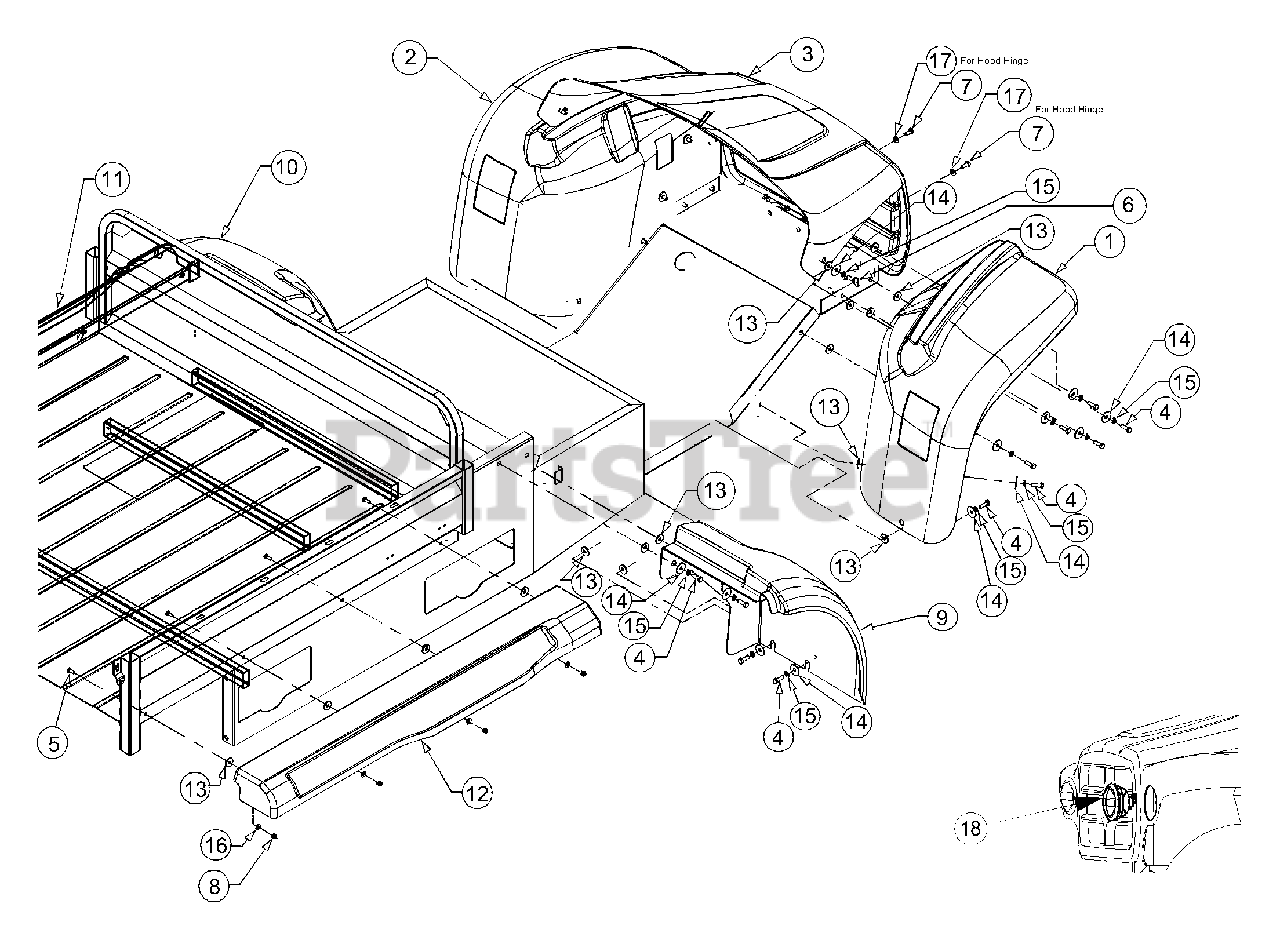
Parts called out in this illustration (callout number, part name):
1	Panel, Front Fender, RH, Camo
2	Panel, Front Fender, LH, Camo
3	Panel, Hood, Camo
4	HexScrew, 5/16-18x1.0Gr5
5	HexScrew, 1/4-20x.75
6	Screw, Thumb Adjust, 5/16-18x1.0
7	HexScrew, 1/4-20
8	HexLock Nut, Nylon, 1/4-20
9	Panel, Rear Fenders, RH
10	Panel, Rear Fender, LH
11	Panel, Bed Skirt, LH
12	Panel, Bed Skirt, RH
13	Washer, Rubber, .310x1.0x.125
14	Flat Washer, .350x1.25x.06
15	Lock Washer, 5/16
16	Flat Washer, .271x.630x.065
17	Flat Washer, .344x.688x.0652
18	Headlight Assembly
